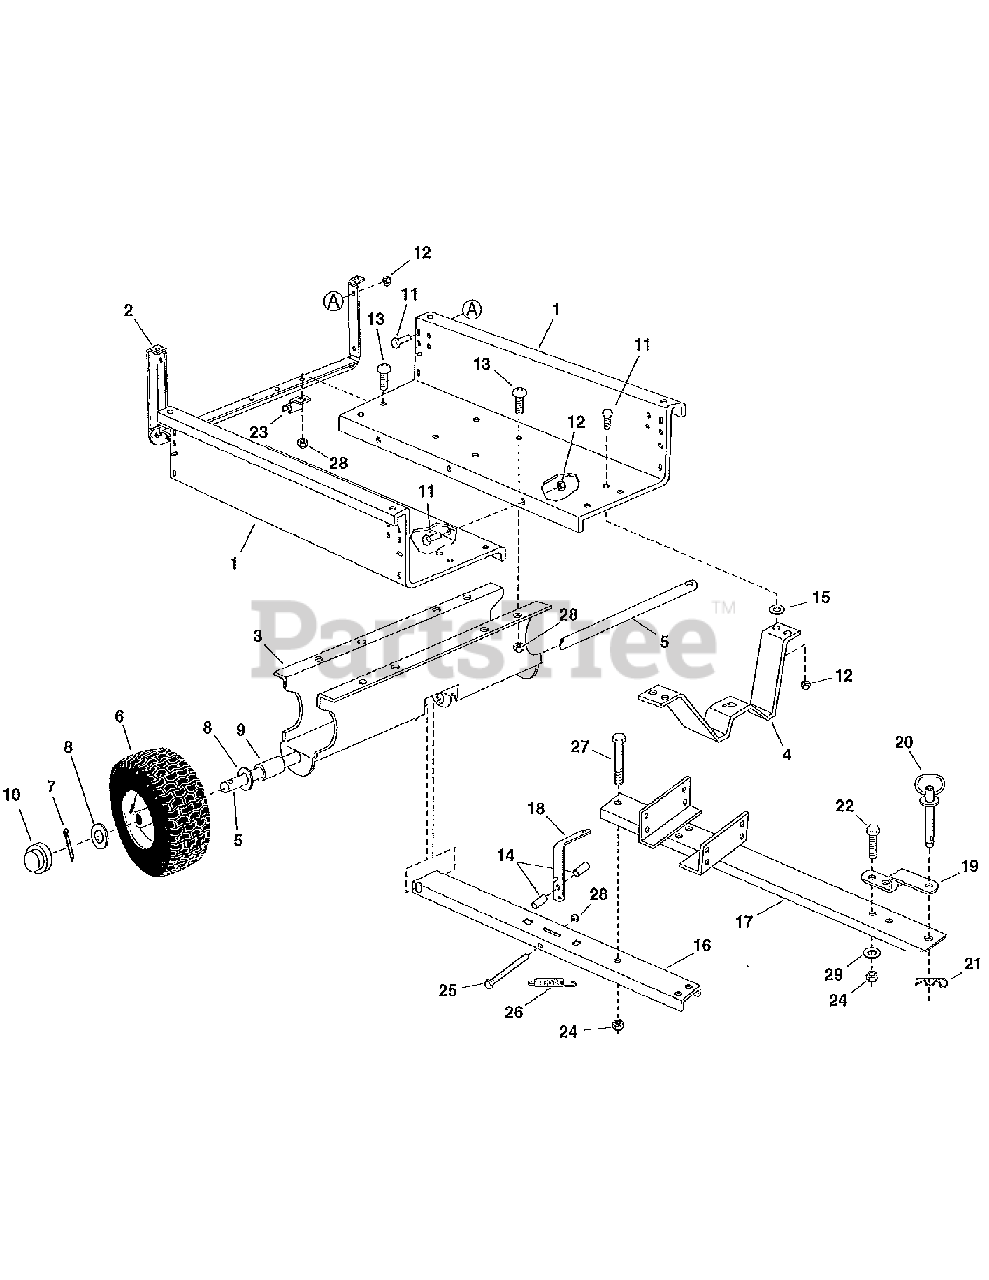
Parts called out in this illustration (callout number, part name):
3	Wheel Support
4	Latch Stand Bracket
5	Axle, Wheel 1" Dia.
6	Wheel w!Tire, 15 x 6.00
7	Cotter Pin, 1/8" Dia. x 1-1/2"
8	Washer, Flat 1"
9	Spacer Tube, 1-1/4" x 2" Lg.
11	Hex Bolt, 1/4-20 x 5/8"
12	Hex Nut, 1/4-20 Nylock
13	Truss Hd. Bolt, 5/16-18 x 3/4"
15	Washer, Flat 1/4"
16	Tongue Weldment Ass'y. (Rear)
17	Tongue Weldment Ass'y. (Front)
18	Latch Lock Lever
19	Hitch Bracket
20	Hitch Pin
21	Pin, Hair Cotter 1/8"
22	Hex Bolt, 3/8-16 x 1-1/4"
23	Door Support
24	Nut, Hex Nylock 3/8-16
25	Hex Bolt, 5/16-18 x 3-3/4"
26	Spring, Extension
27	Hex Bolt, 3/8-16 x 3"
28	Hex Nut, 5/16-18 Nylock
29	Washer, 3/8"
